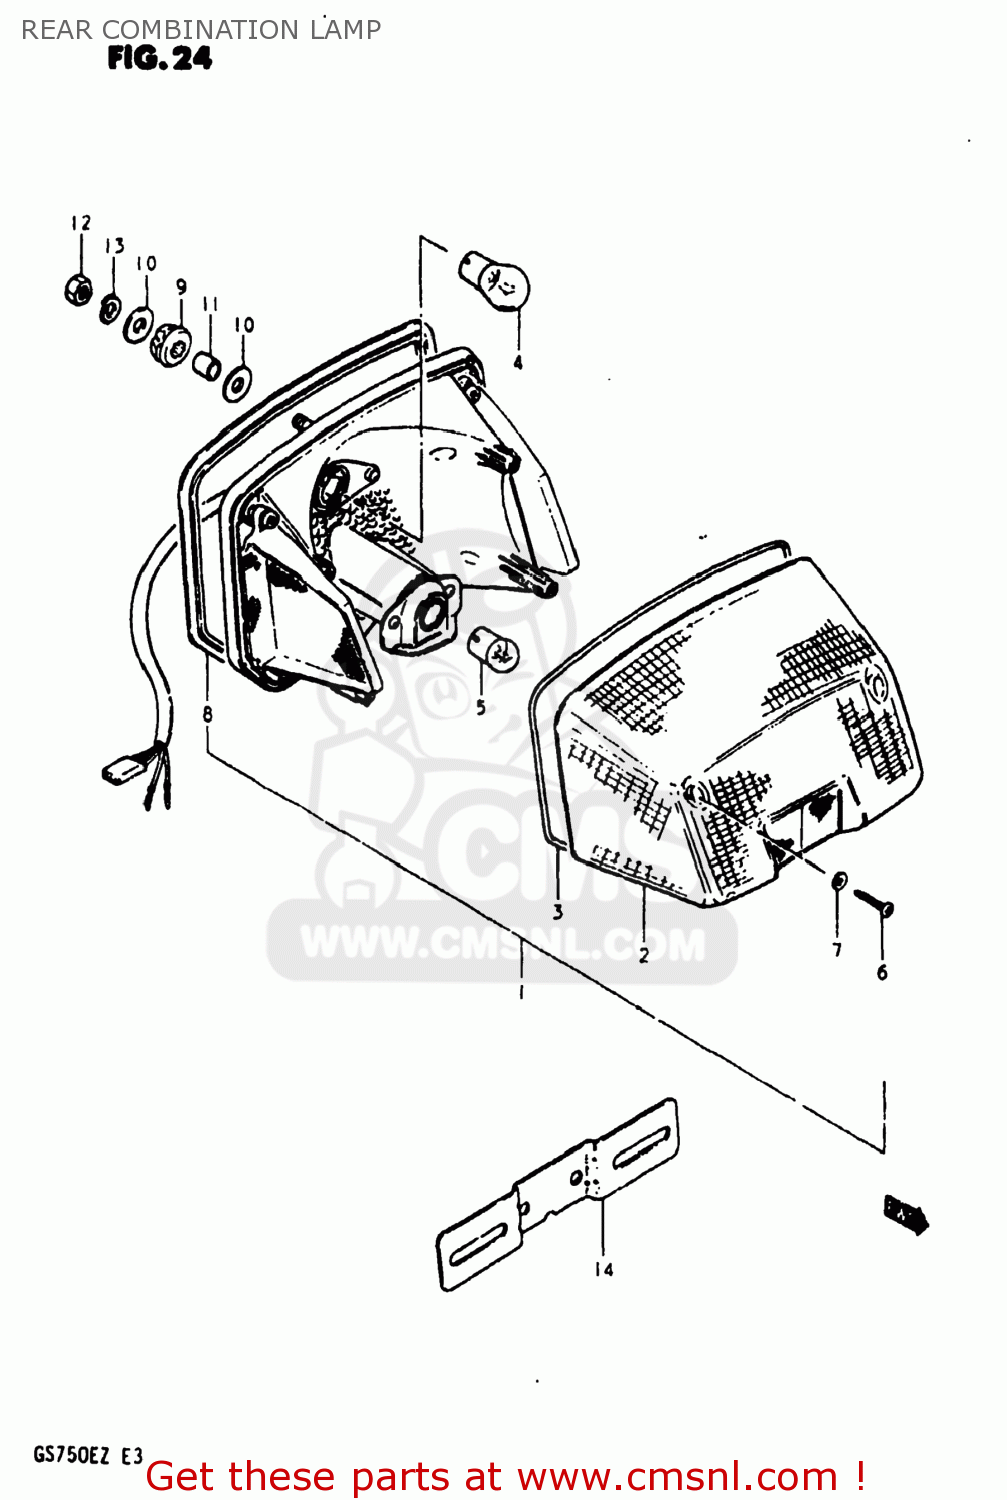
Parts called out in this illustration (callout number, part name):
1	LAMP ASSEMBLY,REAR COMBINATION
2	LENS
3	GASKET (NAS)
4	BULB(12V23W)
5	BULB
6	SCREW
7	GASKET (NAS)
8	GASKET,REAR COMBINATION LAMP
9	CUSHION
10	WASHER
11	SPACER (6.8X10X11.5)
12	NUT
13	LOCK WASHER
14	PLATE,REAR LICENSE
